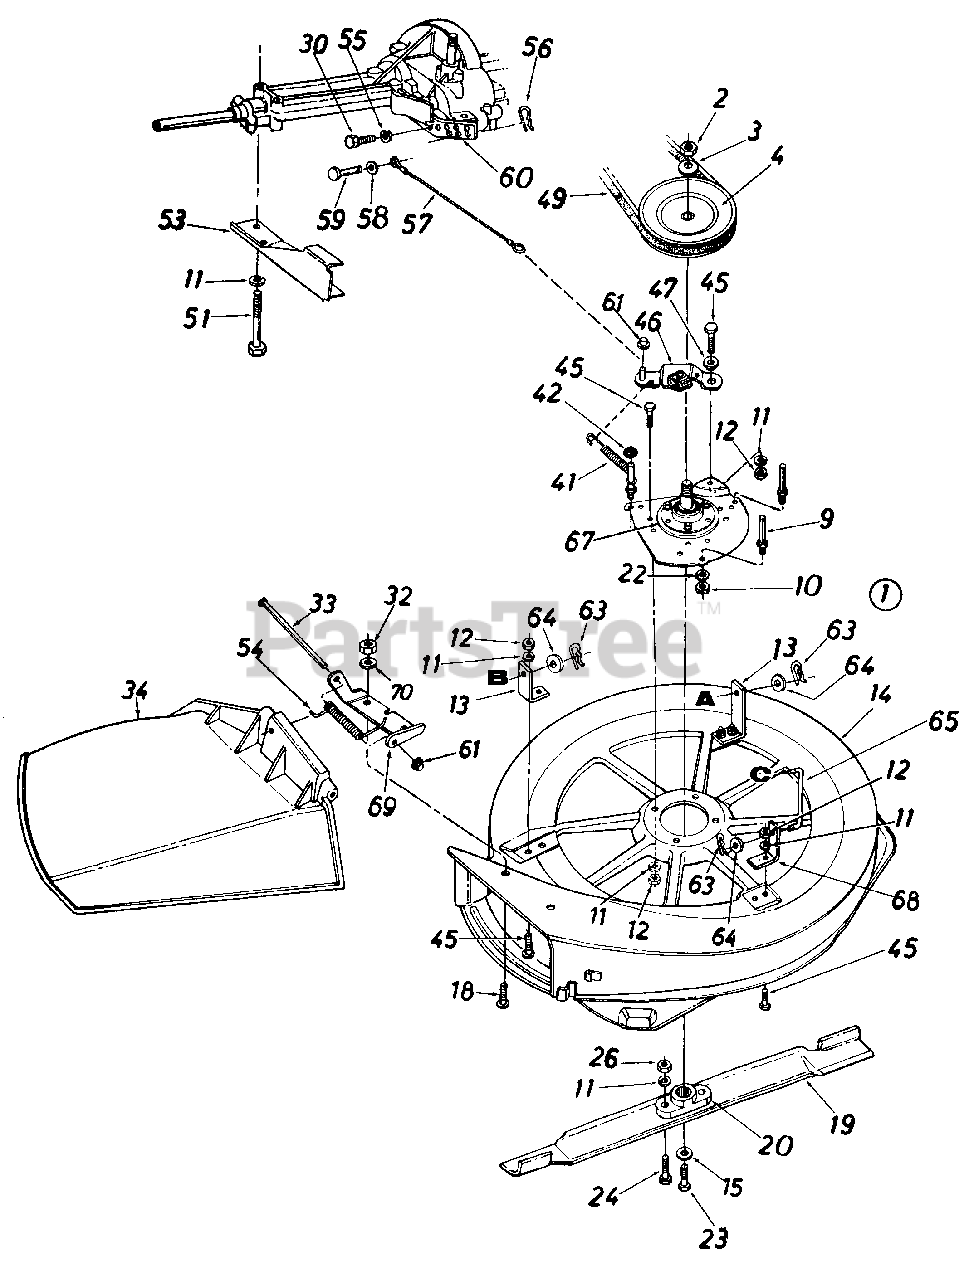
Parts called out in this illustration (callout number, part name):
1	30" S.D. Deck Ass'y. Comp.
2	Hex Jam Nut 5/8-18 Thd.
3	Bell-Wash. .630" I.D. x 1.25"
4	5/8 V-Pulley .75" I.D. x .7"
9	Stud 3/8-16 x 2.75" Lg.
10	Hex Jam Nut 3/8-16 Thd.
11	L-Wash. 5/16" I.D.
12	Hex Nut 5/16-18 Thd.
18	Truss Mach. Scr. 1/4-20 x . 75" Lg .
19	30" High Lift Blade
20	Blade Adapter
22	L-Wash. 3/8" I.D.
23	Hex Bolt 3/8-24 x 1.0
24	Hex Bolt 5/16-24 x 1.0" Lg.
26	Hex Nut 5/16-24 Thd.
30	Hex Bolt 1/4-20 x .60" Lg.
32	Hex Nut 1/4-20 Thd.
33	Hinge Pin
34	Chute Ass'y. Comp.
41	Extension Spring
42	Push Speed Nut
45	Hex Bolt 5/16-18 x .75"
46	Blade Brake Brkt. Ass'y.
47	Shoulder Spacer .500" Dia.
49	"V"-Belt
51	Hex Bolt 5/16-18 x 2.75"
55	L-Wash. 1/4" I.D.
56	Int. Cot. Pin 5/16" Dia.
57	Brake Cable 9.75" Lg.
58	Fl-Wash. .281" I.D. x .50"
59	Clevis Pin 1/4' Dia.
60	Lower Inside Belt Guard
61	Cap Speed Nut 1/4 Rod
63	Int. Cotter Pin 1/2" Dia.
64	Fl-Wash. .531" I.D. x .930"
65	Deck Link 3.9" Lg.
67	Blade Spindle Ass'y. Comp.
68	Weld Bracket
69	Hinge Mtg. Brkt.
70	Bell-Wash. 1/4" I.D.
